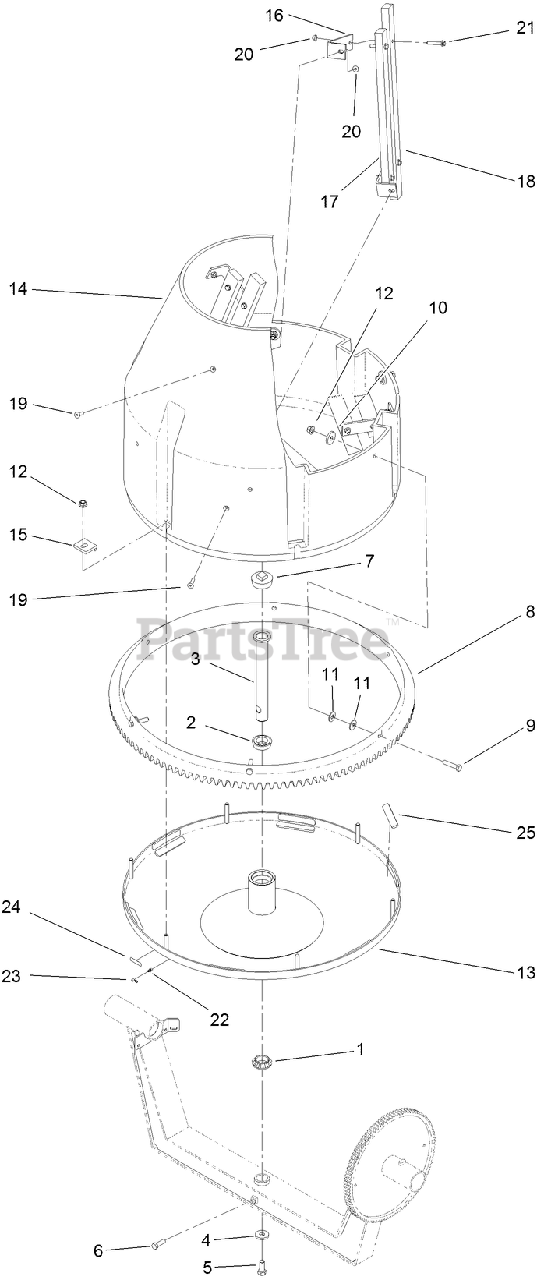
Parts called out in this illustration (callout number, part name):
1	BEARING-ROLLER
2	BEARING
3	SPINDLE
4	WASHER-FLAT
5	SCREW-HH
6	SCREW-HH
8	GEAR-RING
9	SCREW-HH
10	WASHER-FLAT
11	WASHER-FLAT
12	NUT-LOCK
15	CLAMP-DRUM
16	BRACKET-PADDLE
17	PADDLE
18	PADDLE
19	SCREW-FH, HEX SOCKET
20	NUT-HF, NI
21	SCREW-HHF
22	FITTING
23	CAP-PLUG
24	DECAL-GREASE
25	PAD-RUBBER
